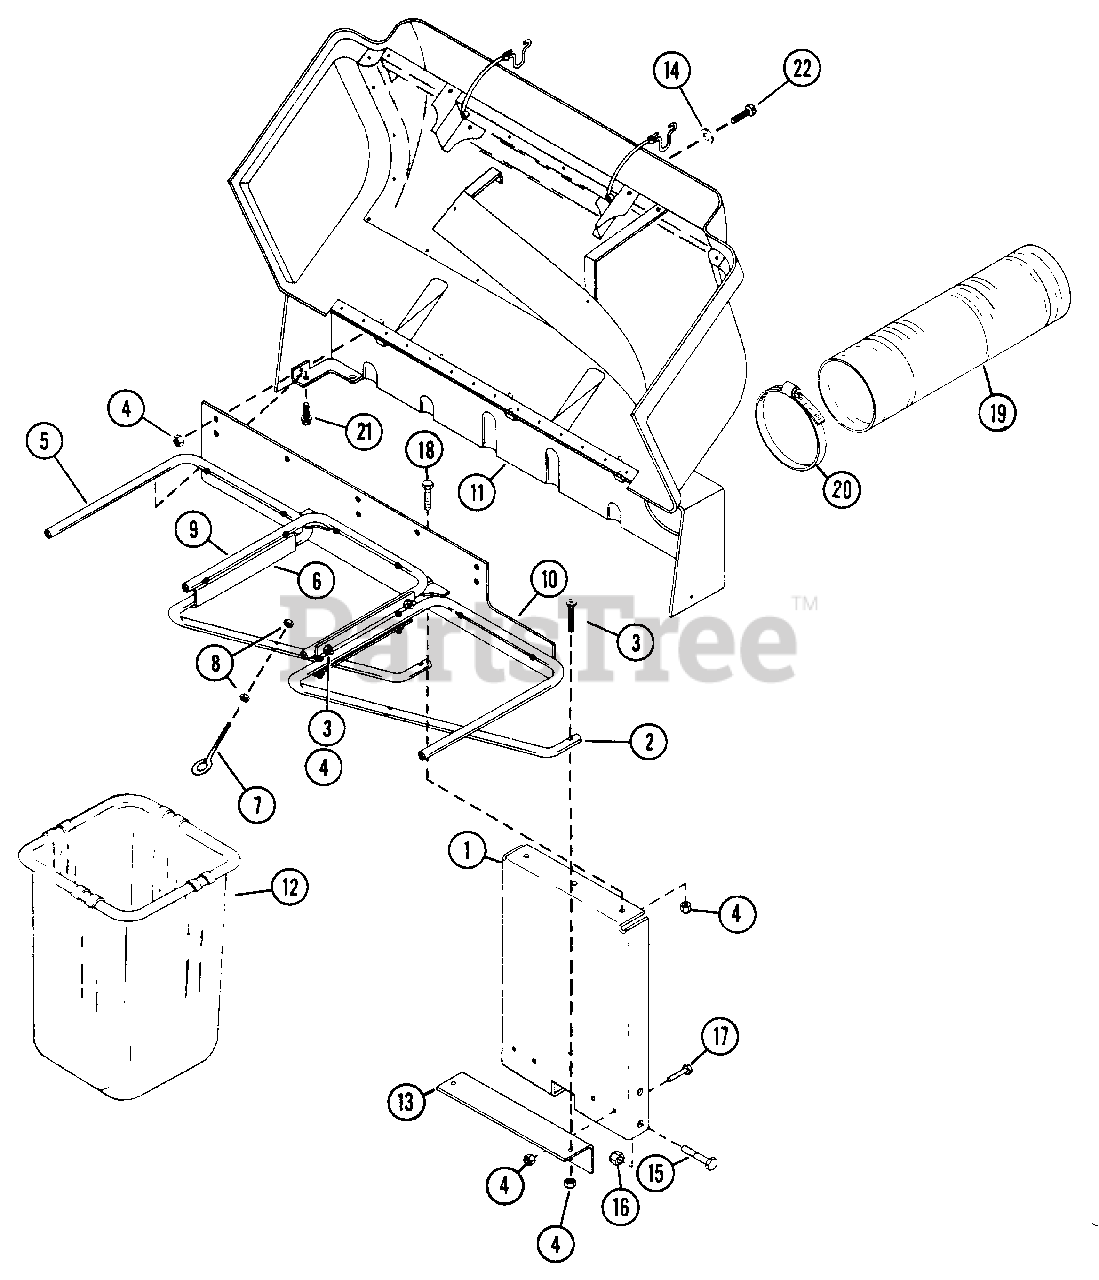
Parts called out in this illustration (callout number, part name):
1	SUPPORT
2	RIGHT TUBE
3	SCREW, MACHINE 5/16-18X1.50
4	NUT, LOCK 5/16-18
5	LEFT TUBE
6	TUBE BRACKET
7	EYEBOLT
8	NUT, LOCK 1/4-20
9	CENTER TUBE
10	MOUNTING BRACKET
11	COVER ASSEMBLY
12	GRASS BAGGER BASKET
13	BRACKET
14	WASHER, .339/.359X1.125X.063 PL
15	BOLT, HEX 1/2-13X1.25
16	NUT, LOCK 1/2-13
17	BOLT, HEX 5/16-18X.75
18	BOLT, HEX 5/16-18X1.00
19	HOSE
20	HOSE CLAMP
21	BOLT, HEX 5/16-18X.50
22	SCREW, MACHINE 5/16-18X.75 T/HD
